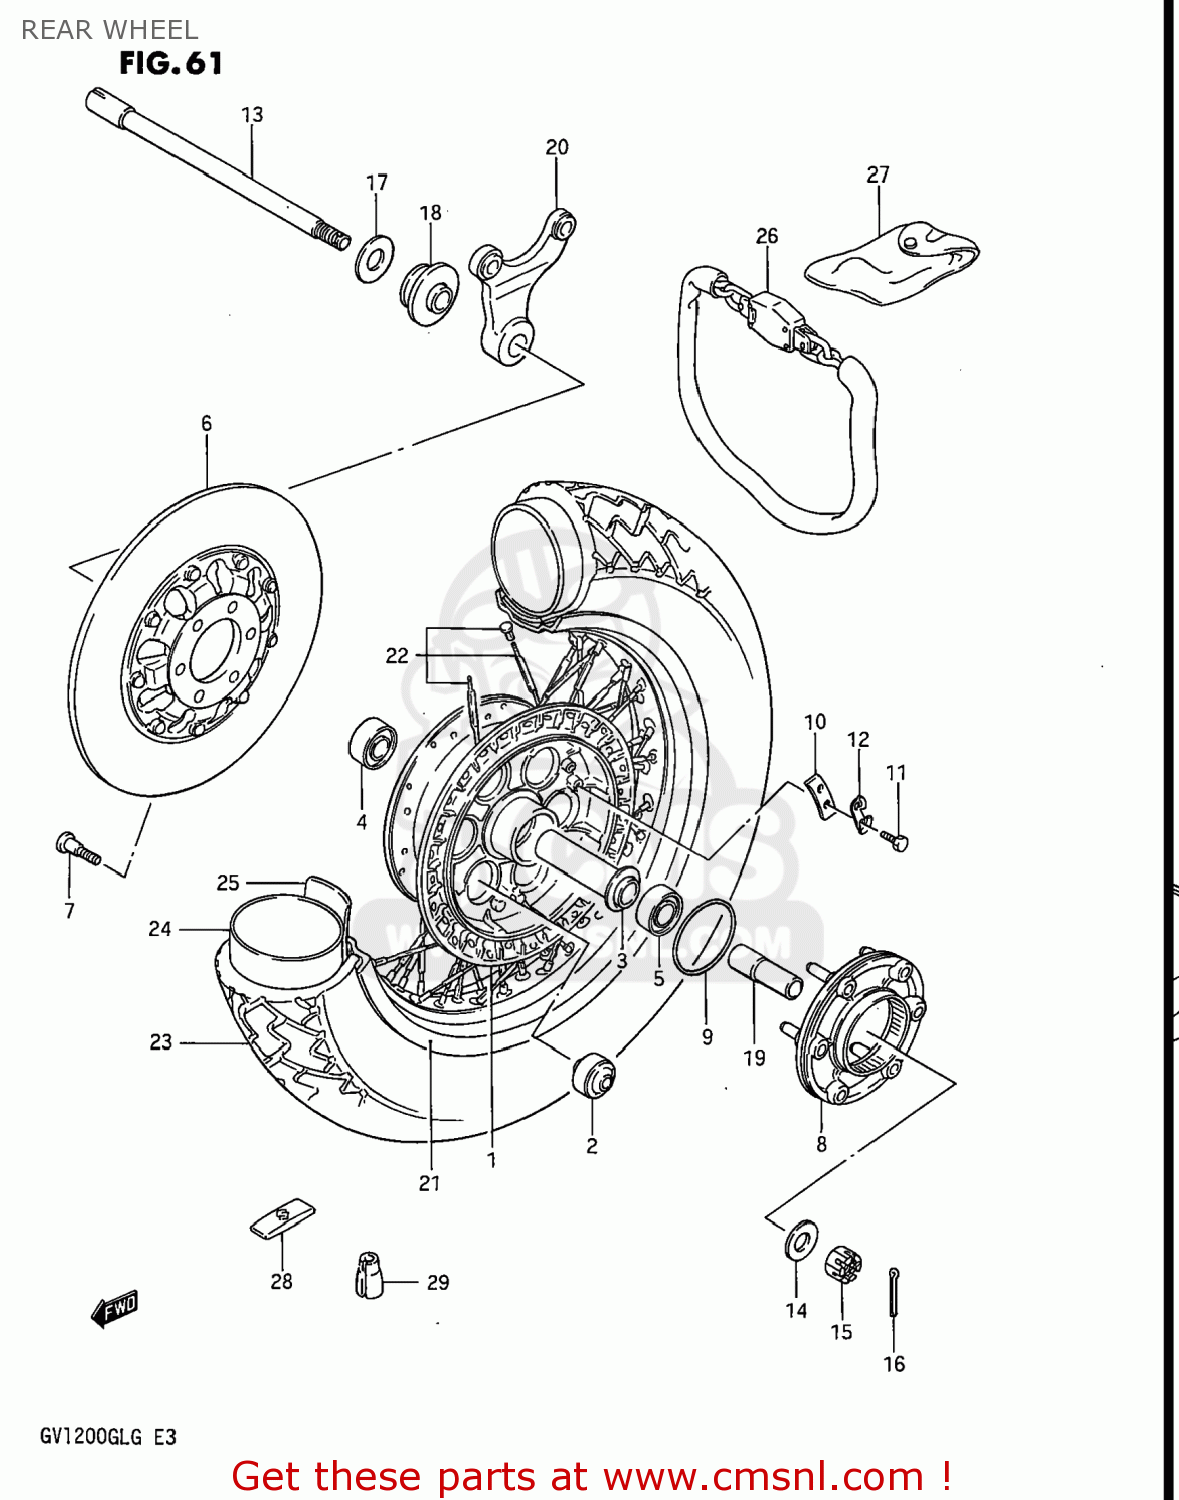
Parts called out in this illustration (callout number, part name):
1	HUB SET,REAR
2	BUSH
3	SPACER,REAR HUB BEARING
4	BEARING
5	BEARING
6	DISC,REAR BRAKE
7	BOLT
8	JOINT ASSY,RR HUB DRIVEN
9	O RING(D:2.1,ID:65)
10	WASHER,THRUST(T:1.6)
11	BOLT(6X16)
12	WASHER
13	AXLE,REAR
14	WASHER(16.5X36X3.2)
15	NUT
16	PIN,COTTER
17	WASHER, RH
18	SPACER,REAR AXLE
19	SPACER,REAR AXLE,LEFT
20	BRACKET,REAR CALIPER
21	RIM,REAR WHEEL
22	SPOKE SET,REAR WHEEL
23	TIRE 140/80-16
24	TUBE ASSY,WHEEL INNER
25	PROTECTOR,WHEEL,INNER
26	CHAIN LOCK ASSY
27	BAG,CHAIN LOCK
28	BALANCER,WHEEL NO.1
29	BALANCER,WHEEL
